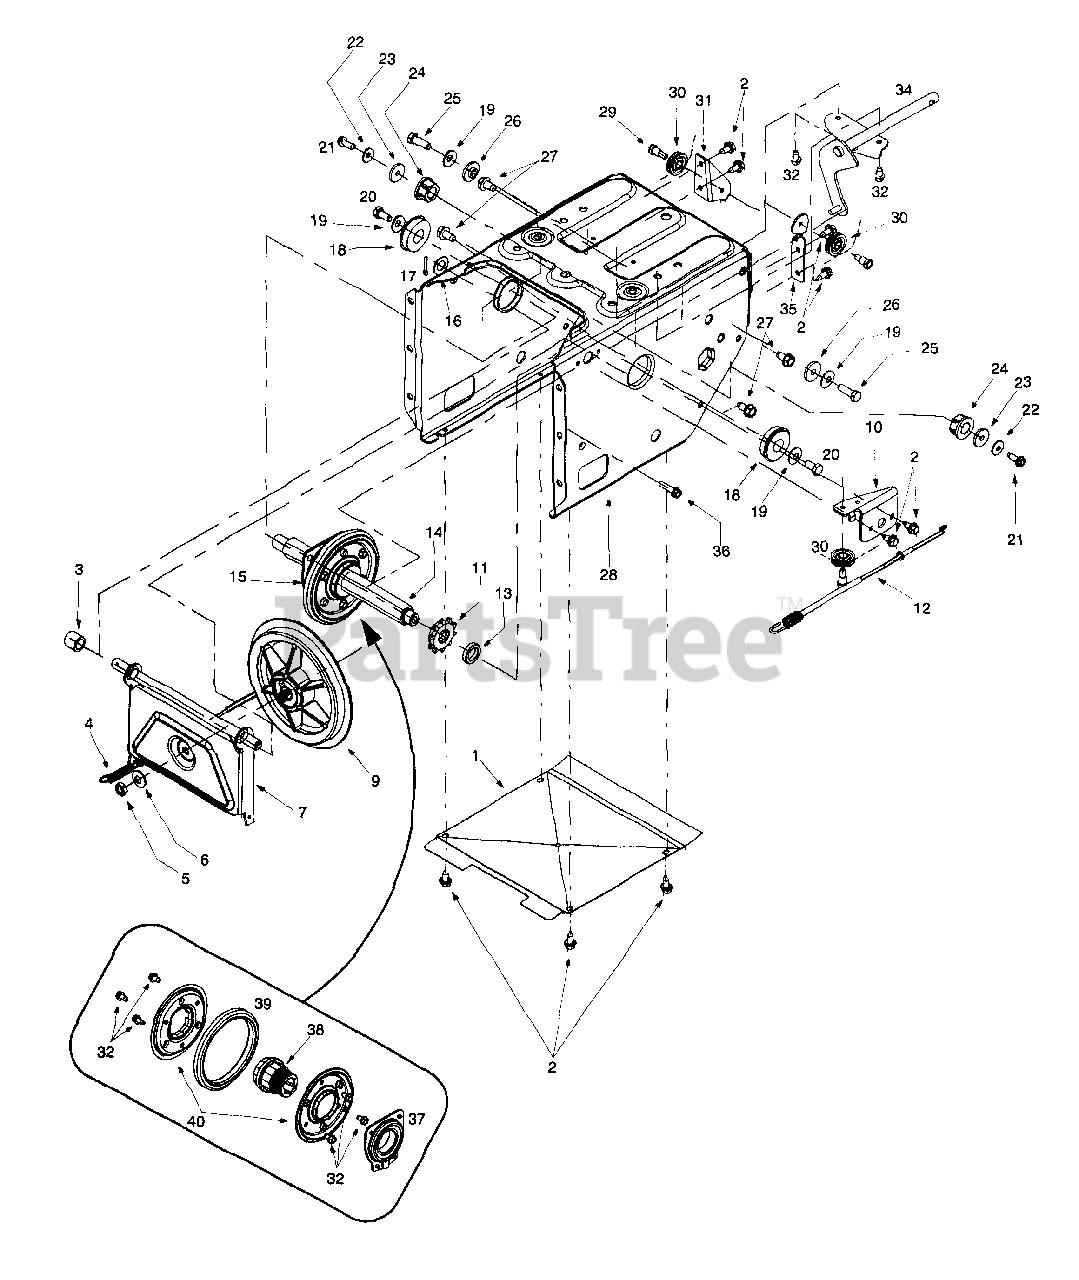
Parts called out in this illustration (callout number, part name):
1	Frame Cover
2	Tap Screw, 1/4-20 x .625
3	Spacer, .508 ID x .75 OD x .68
4	Ext. Spring
4	Drive Cable, 39.88"
5	Jam Nut, 3/8-24
6	Bell Washer, .401 x .87 x .063
7	Friction Wheel Support Bracket Assembly
9	Friction Disc
10	Front Support Guide Bracket
11	Ten-Tooth Sprocket
12	Auger Cable, 44.75"
13	Spacer, .675 ID x 1 OD x .23
14	Hex Track Shaft
15	Friction Wheel Assembly
16	Flat Washer, .536 ID x .93 OD x .05
17	Cotter Pin
18	Ball Bearing
19	Bell Washer, .34 ID x .872 OD
20	Hex Cap Screw, 5/16-18 x .625
21	Tap Screw, 1/4-20 x .75
22	Bell Washer, .265 x .75 x .062
23	Flat Washer, 1/4 ID x .93 OD x .12
24	Hex Flange Bearing
25	Hex Cap Screw, 5/16-18 x 1
26	Shoulder Spacer
27	Tap Screw, 5/16-18 x .625
28	Frame Assembly
29	Spacer
30	Cable Roller
31	Drive Cable Guide Bracket
32	Tap Screw, 1/4-20 x .5
34	Shift Rod Assembly
35	Auger Cable Guide Bracket
36	Tap Screw, 1/4-20 x 1
37	Friction Wheel Bearing
38	Friction Wheel Hub
39	Friction Wheel Rubber
40	Friction Plate
